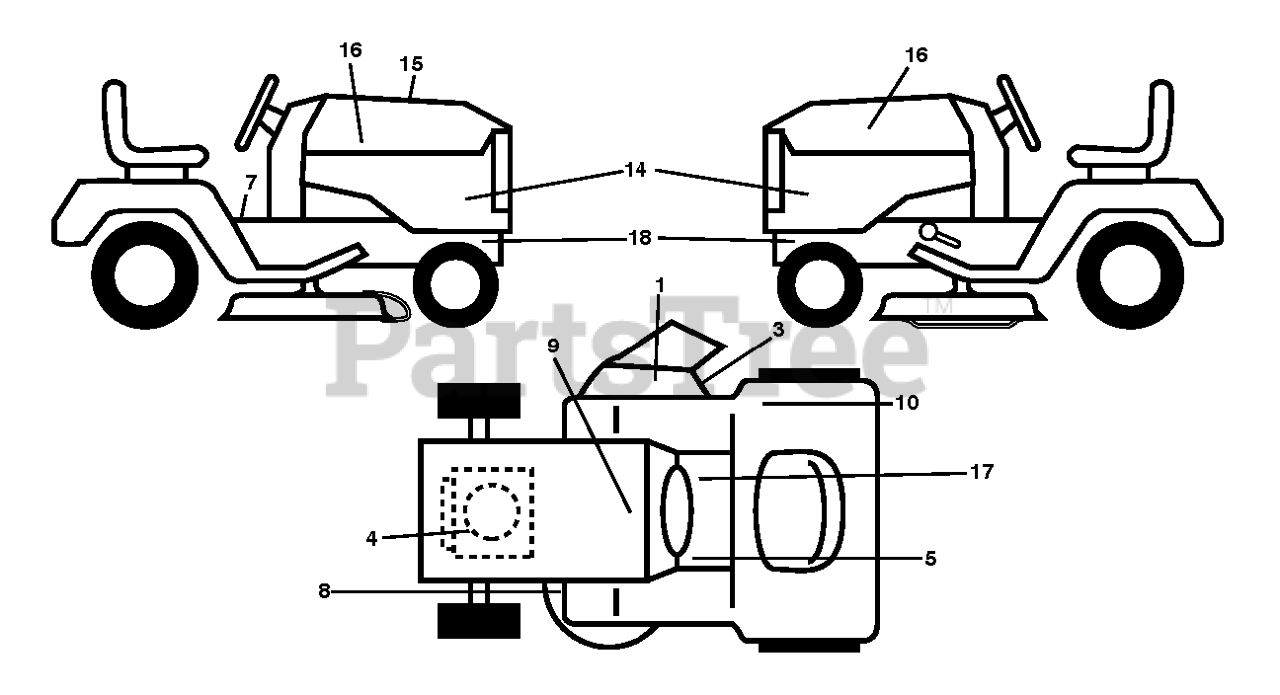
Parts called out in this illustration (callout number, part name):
3	DECAL.DFLCTR.WARNNG.CTFNGR.SYM
4	DECAL.ENGINE.WARNING
5	DECAL.FNDR.SDLE.BRAKE.CLUTCH.6
7	DECAL.READ.OWN.MAN.SYMBOL.LT
8	DECAL.MOWER.SCH.48/54.PREM
9	DECAL BTRY SYMBOLS
10	DECAL.FENDER.105DB/CE.
11	DECAL.CUTFINGER.CE.02
15	DECAL.RPL.KAW.FS.TGW.48.HG700
16	DECAL.BADGE.170MM.TEXTLOGO.
17	DECAL.PARKING.BRAKE.SADDLE.LT
18	DECAL.CHASSIS.HOT.MUFFLER
